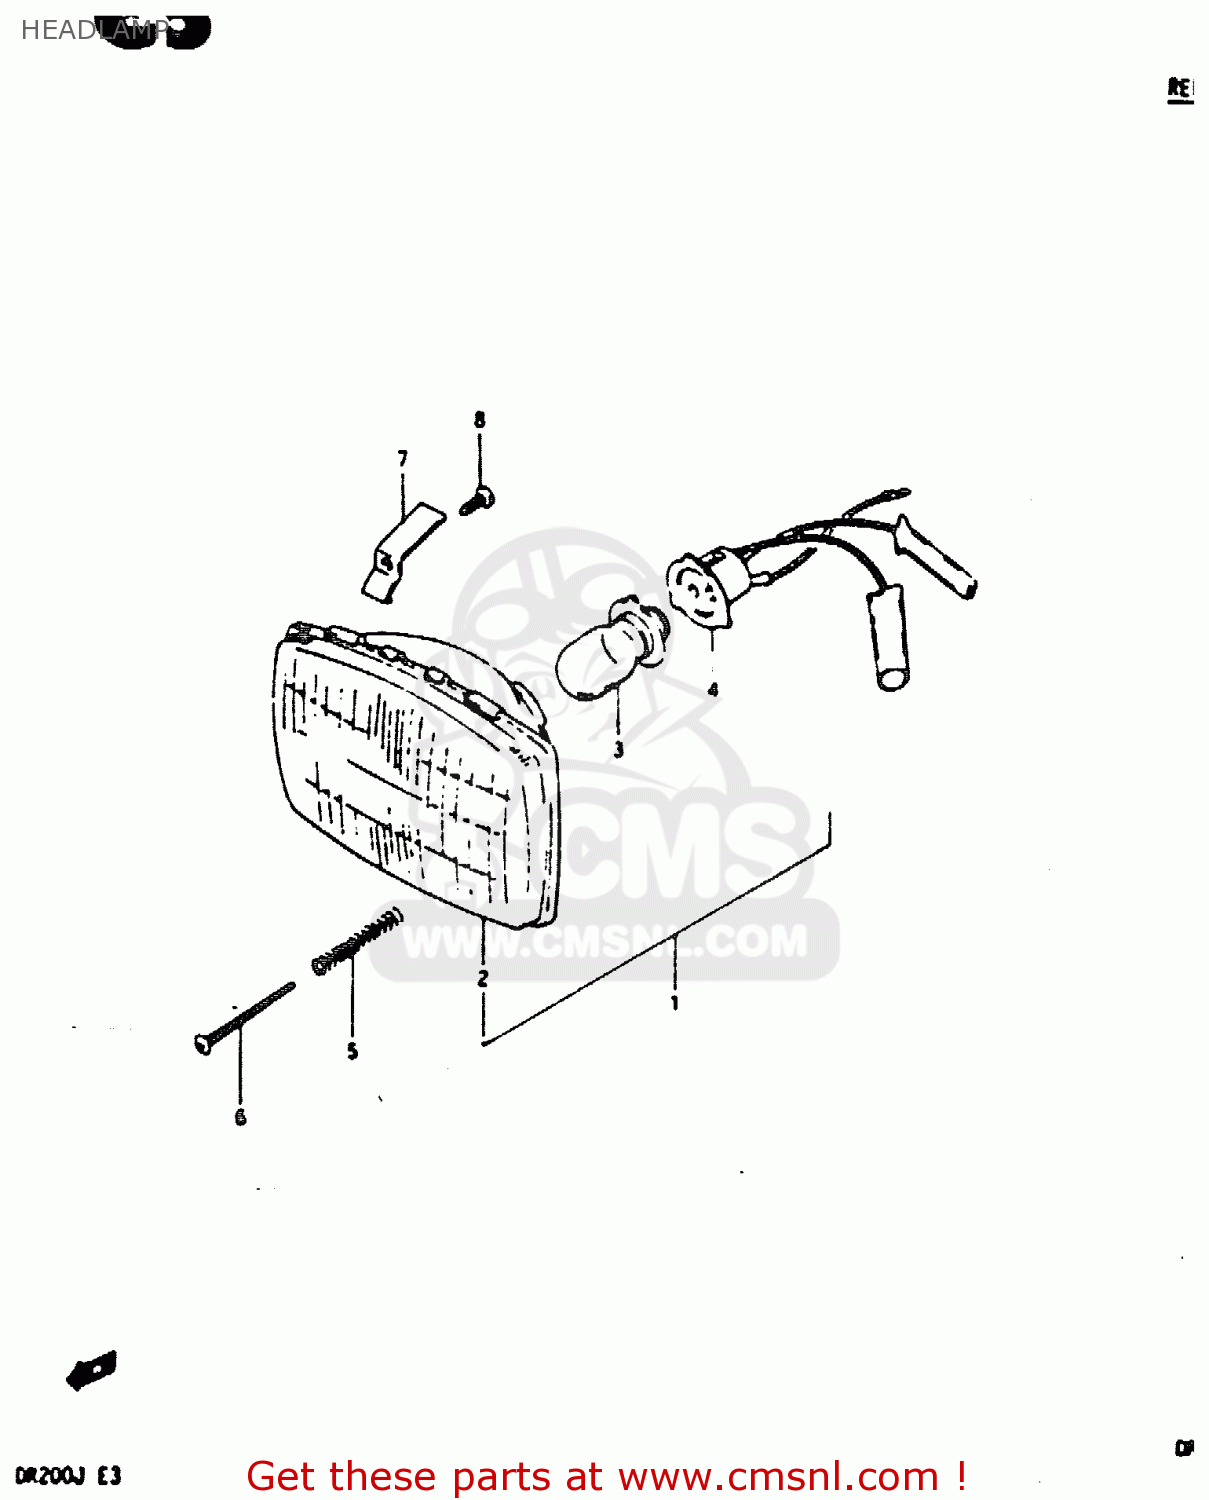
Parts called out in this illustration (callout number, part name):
1	HEADLAMP ASSEMBLY
2	LAMP UNIT
3	BULB
4	SOCKET,HEADLAMP
5	SPRING,HEAD LAMP ADJUSTER
6	SCREW,HEADLAMP ADJUST
7	SPRING
8	SPRING,HEADLAMP ADJUST
